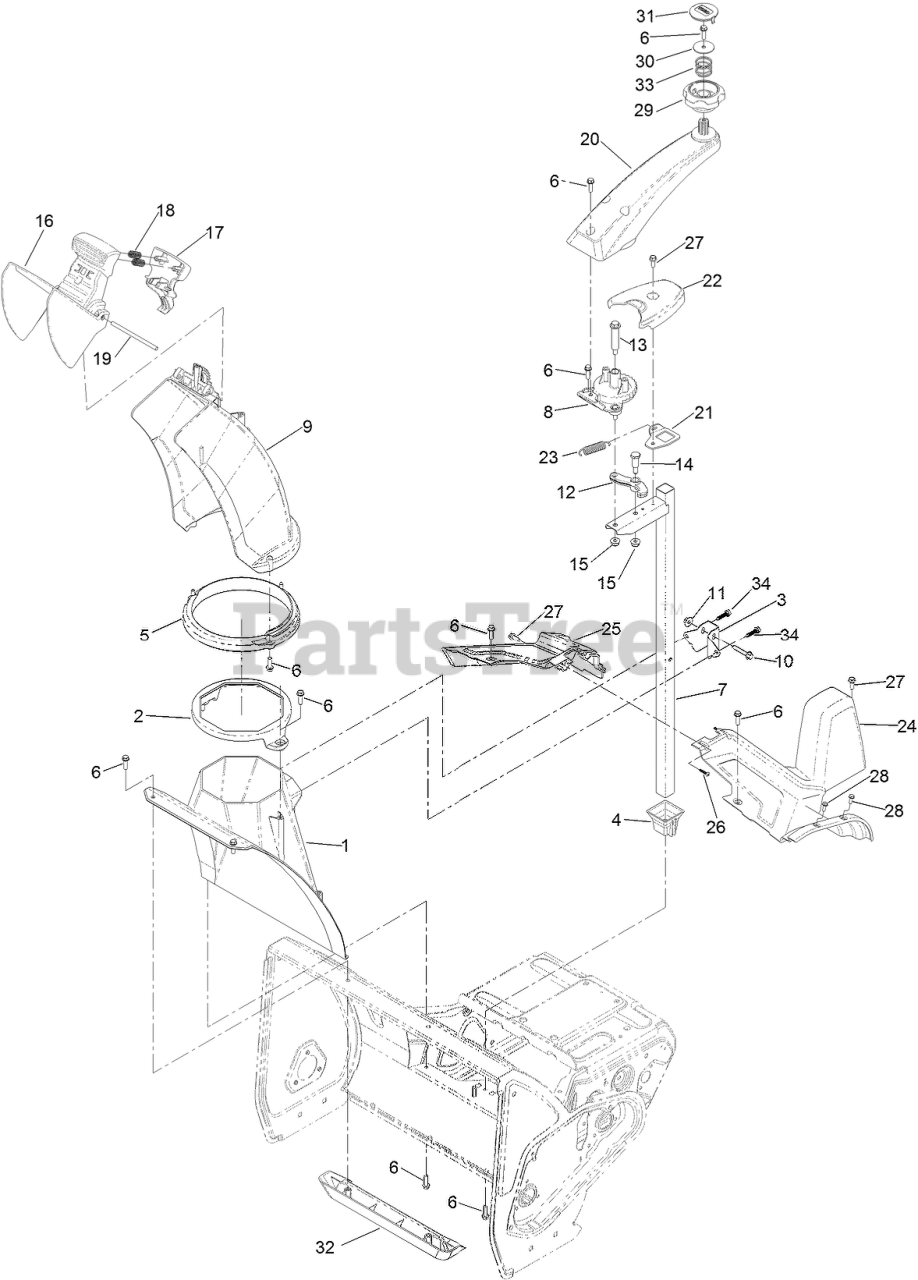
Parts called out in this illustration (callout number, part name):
1	CHUTE-LOWER
2	GUIDE-CHUTE
3	BRACKET-POST, SUPPORT (CHUTE)
4	RETAINER- POST, CHUTE
5	RING-CHUTE
6	SCREW-HWH
7	POST-CHUTE, MANUAL
8	GEAR-CHUTE, MANUAL
9	CHUTE-SNOW, ASM
10	SCREW-HHF
11	NUT-HEX FLG
12	LATCH-CHUTE
13	BOLT-SHOULDER
14	SCREW-SHOULDER
15	NUT-HF, NI
16	DEFLECTOR-CHUTE
17	TRIGGER-DEFLECTOR
18	SPRING-COMPRESSION
19	ROD-COVER
20	HANDLE-CHUTE, MANUAL
21	SUPPORT-SPRING
22	COVER-SPRING
23	SPRING-EXTENSION
24	SHROUD-UPPER, LH
25	SHROUD-LOWER, RH
26	SCREW-PPH
27	SCREW-HWH
28	SCREW-HWH
29	KNOB-CONTROL, CHUTE
30	WASHER-FLAT
31	INSERT-KNOB
32	KICKER-HOUSING
33	SPRING-COMPRESSION
34	SCREW-FLANGE, PLASTIC
